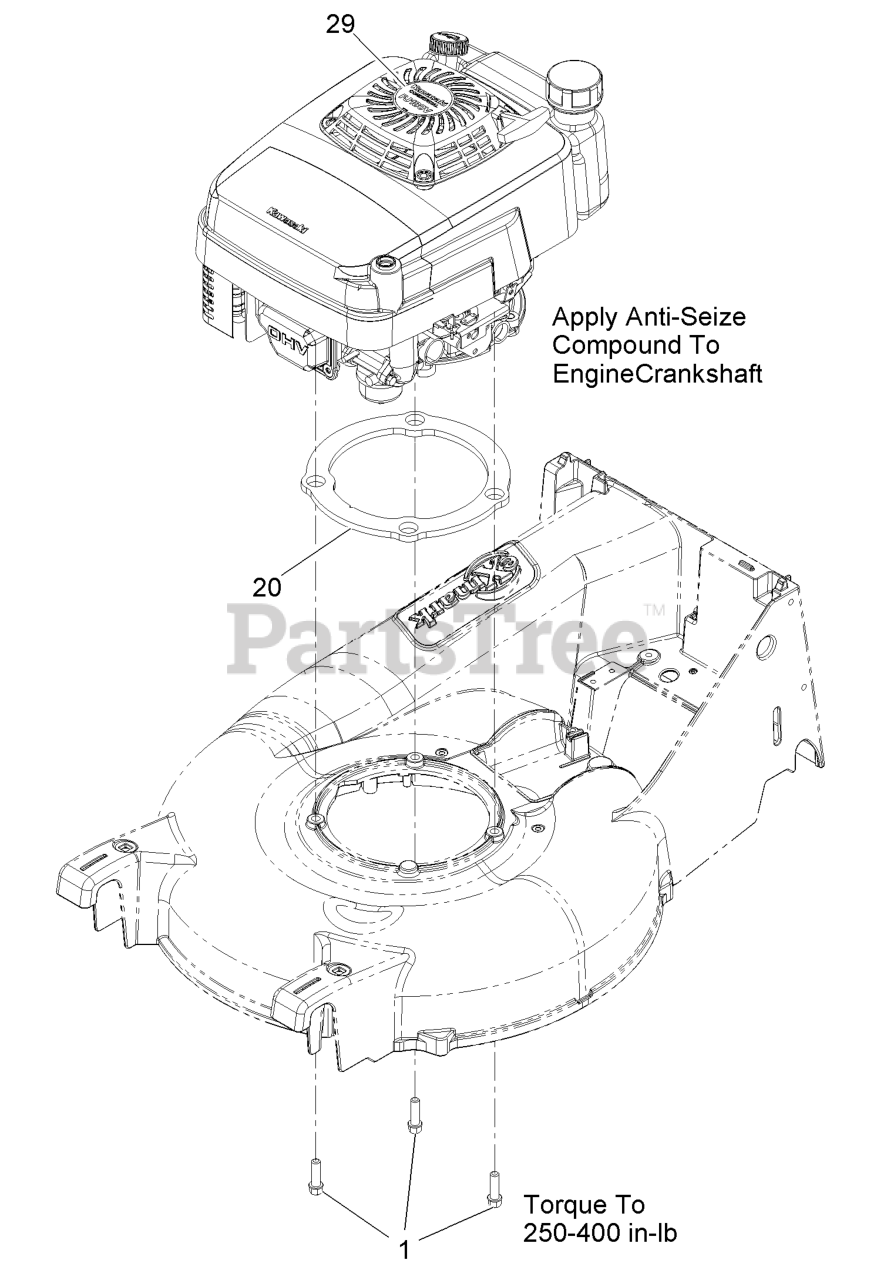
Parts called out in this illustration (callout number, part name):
1	SCREW-TAPTITE
20	GASKET,DECK
29	DECAL-RECOIL
